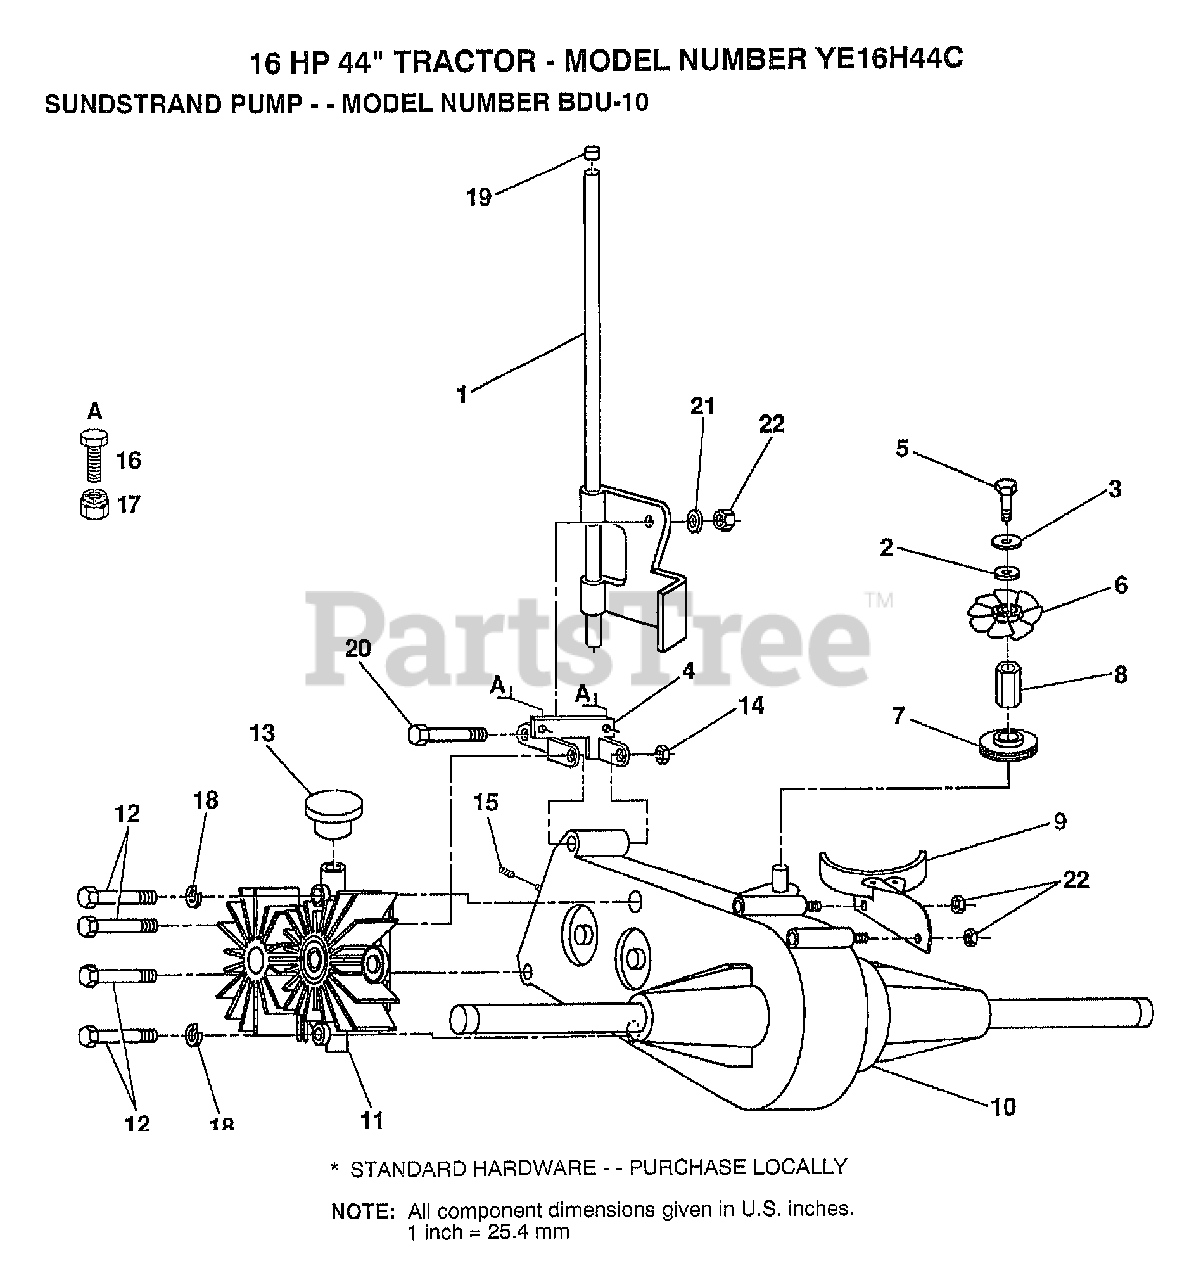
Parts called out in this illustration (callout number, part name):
1	CONTROL ASSY
2	WASHER
3	LOCKWASHER
4	BRACKET
6	FAN
7	PULLEY TRANSAXLE
8	STANDOFF
9	GUARD ASSY
10	TRANSAXLE.AGRIFAB
11	PUMP.BDU-10S-114
12	BOLT
13	PUMP.2003081.
15	SPRING
18	LOCKWASHER
19	PLUNGER CAP T
20	BOLT T
21	WASHER T
